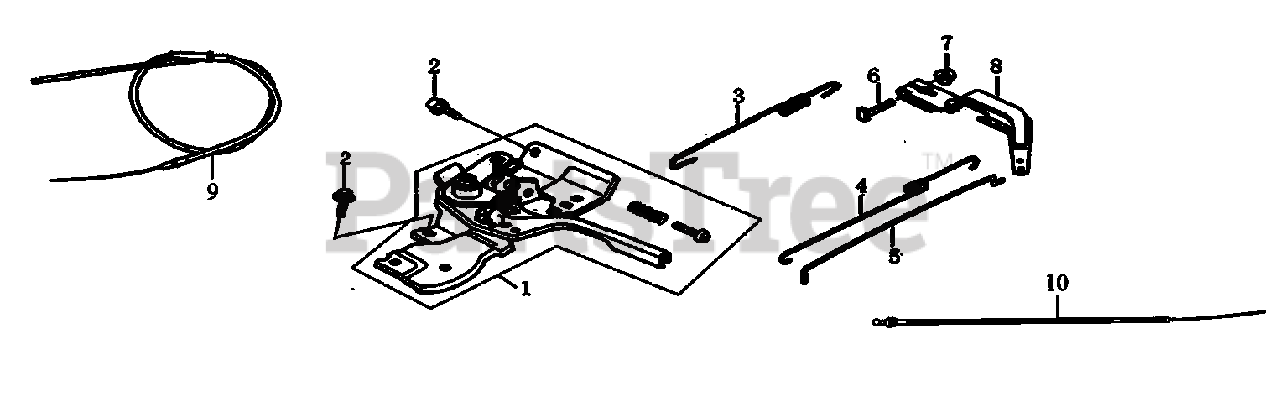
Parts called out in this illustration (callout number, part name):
1	CONTROL ASSY.
2	BOLT, FLANGE
3	SPRING, GOVERNOR
4	SPRING, THROTTLE RETURN
5	ROD, GOVERNOR
6	BOLT, GOVERNOR ARM M6X21
7	NUT, FLANGE
8	ARM, GOVERNOR
9	CABLE, THROTTLE
10	CABLE, CHOKE
